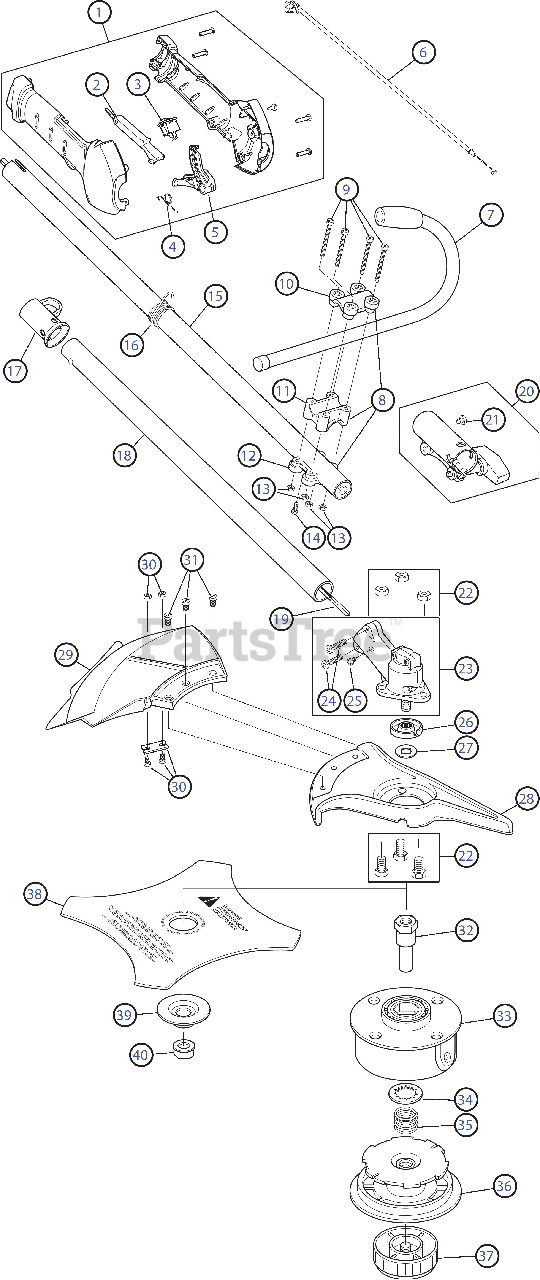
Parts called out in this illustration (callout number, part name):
1	Throttle Housing Assembly
2	Throttle Trigger Lock-Out
3	Switch Assembly
4	Throttle Trigger Spring
5	Throttle Trigger
6	Throttle Cable Assembly
7	J-Handle Assembly
8	J-Handle Bracket Assembly
10	Upper Handle Clamp
11	Middle Handle Clamp
12	Lower Handle Clamp
14	Anti-Rotation Screw
15	Upper Drive Shaft Housing Assembly
16	Harness Clip
18	Lower Drive Shaft Housing Assembly
19	Lower Flexible Drive Shaft
20	Split Boom Coupler
22	Shield Mount Screw Assembly
23	2 Piece Gearbox Assembly
24	Gearbox Mounting Hardware
25	Anti-Rotation Screw
26	Blade Driver
28	Blade Shield / Shield Mount
29	Shield Assembly
30	Blade Assembly
31	Shield Mounting Screw
32	Spool Shaft
33	Outer Spool Assembly
34	Retainer
37	Bump Head Knob Assembly
38	4-Tooth Blade
39	Retaining Washer
